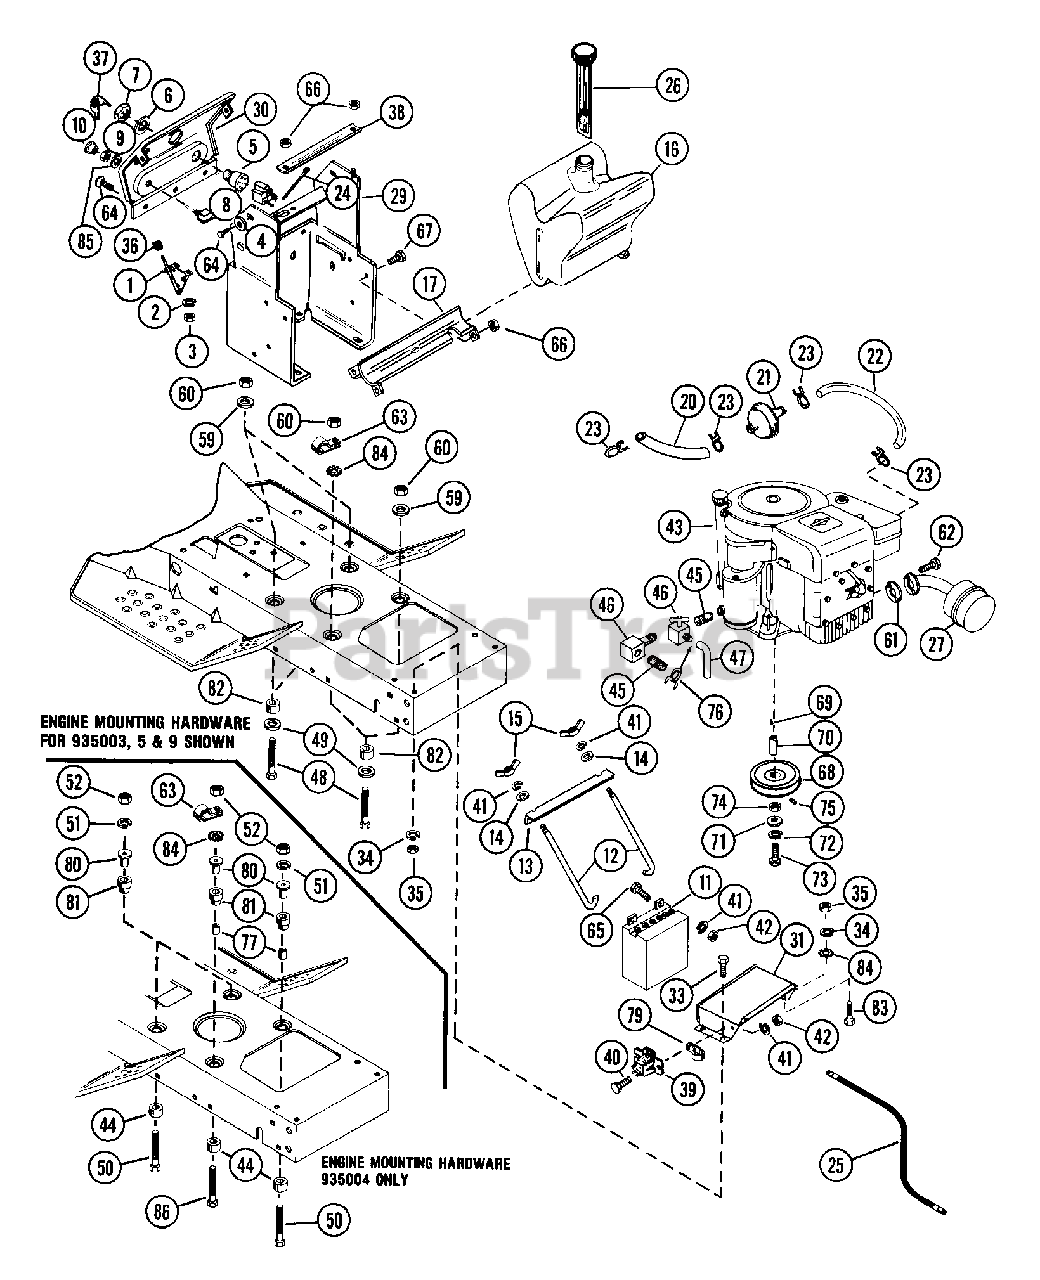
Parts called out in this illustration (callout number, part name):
1	THROTTLE
2	WSHR-LK 10X.047 MED PL
3	NUT-HEX 10-24 PL
4	WSHR-FL-STL .250X.562X.049 PL
5	IGNITION SWITCH
6	WSHR-LK-INT .563X.040 PL
7	NUT .562-24
8	LIGHT SWITCH
9	NUT .50-20 PL
11	BATTERY
12	HOOK BOLT
13	BATTERY HOLD DOWN
14	WSHR-FL-STL.312X.734X.065PL
15	NUT-WING .250-20 YWZC
16	FUEL TANK
17	LOWER TANK SUPPORT
20	PARTS MANUAL - PM-31
21	FUEL FILTER
22	PARTS MANUAL - PM-31
23	CLAMP-HOSE WIR.490/.510X.092#8
24	TIE DOWN
25	GROUND CABLE .31X22.00X.31
26	FUEL GAUGE
27	EXHAUST MUFFLER
29	DASH BASE WITH DECALS
30	DASH
31	BATTERY STAND
32	FRAME W/DECALS
33	BLT-HEX .31-18X.75 PL GR2
34	WSHR-LK .312X.097 PL HVY
35	NUT-HEX .312-18
37	KEYS
38	CLAMP STRAP
39	SOLENOID
40	BLT-HEX .25-20X1.00 GR2
41	WSHR-LK .250X.077 HVY PL
42	NUT-HEX .250-20 PL
43	ENGINE
44	TOP ISOLATION MOUNT
45	BUSHING
46	DRAIN LOCK
46	PIPE FITTING 90 DEG. X 3/8 ELB
47	TUBE
48	BLT-HEX .31-18X2.00 PL GR5
49	WSHR-FL-STL .312X1.62X.13
50	BLT-HEX .31-18X2.50 PL GR2
51	WSHR-LK .312X.097 PL HVY
52	NUT-HEX .312-18
59	WSHR-FL-STL.312X.734X.065PL
60	NUT-LK-TOP .312-18 GR C PL
61	GASKET - EXHAUST FLANGE
62	SCR-SKH .31-18X.75 PL
63	J-CLAMP
64	SCR-SHT.MET10-16X.375 HWH PL B
65	BLT-HEX .25-20X.75 PL GR2
66	NUT-LK TOP .250-20 PL
67	BLT-HEX .25-20X.50 PL GR2
68	PLY-? 3.50X1.0
69	KEY-SQ .25X1.0X.25 SAE 8630
70	BEARING SPACER 1.032X1.25X1.78
71	WSHR-FL-STL .469X1.380X.125
72	WSHR-LK .438X.133 HVY
73	BLT-HEX .44-20X1.00 GR5
74	SPACER 1.032X1.250X.312
75	SCR-SET .32-18X.25 SKHCUP OH
76	HOSE CLAMP
77	RUBBER BUSHING
80	SPACER-SHOULDER
81	BOTTOM ISOLATION MOUNT
82	ENGINE SPACER
83	BLT-HEX .31-18X.75 PL GR2
84	WSHR-LK-EXT .313X.030 PL
85	WSHR-FL-STL .382X.812X.023 PL
86	BLT-HEX .31-18X2.75 PL GR2
86	WSHR-LK .312X.097 PL HVY
86	NUT-JAM .312-24 PL
86	WSHR-LK 10X.047 MED PL
86	NUT 10-32 PL
